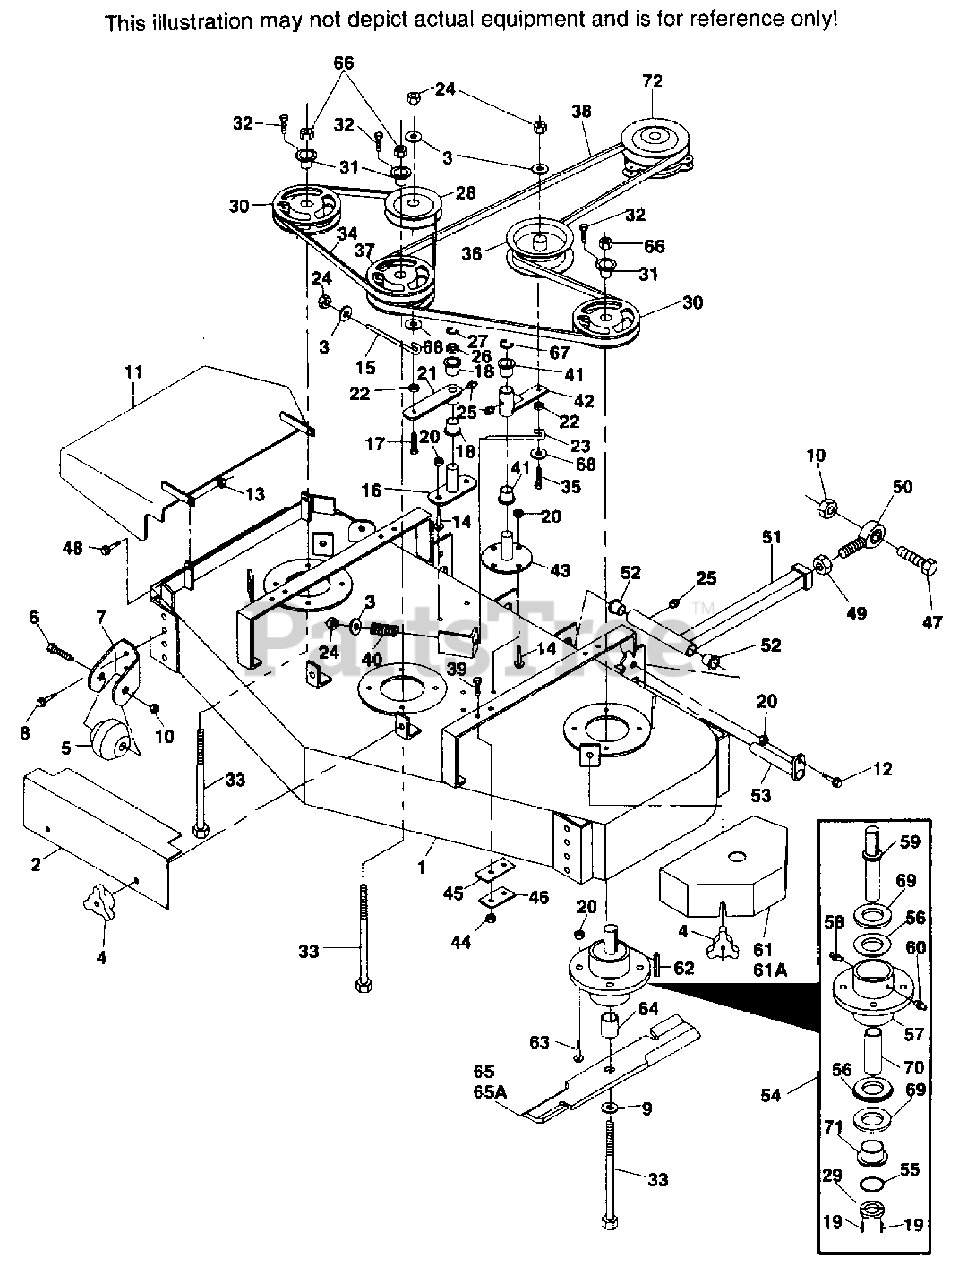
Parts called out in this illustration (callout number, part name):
1	CUTTER DECK(INCLUDES DECALS)
2	BELT COVER, FRONT
3	FLATWASHER, 3/8" SPECIAL
4	WING NUT, 3/8-16
5	ANTI-SCALP WHEEL
7	ANTI-SCALP WHEEL BRACKET
8	CAP SCREW, 3/8-16 X 1" SERRATED FLANGE HEX
9	FLATWASHER 5/8"(.688 X 1.75 X .134)
10	HEX NUT, 5/8-11 ELASTIC STOP
11	DISCHARGE CHUTE
12	CAP SCREW, 5/16-18 X 1" SERRATED FLANGE HEX
13	HEX NUT, 5/16-18 ELASTIC STOP
14	CAP SCREW, 5/16-18 X 3/4" SERRATED FLANGE HEX
15	"J" ROD
16	IDLER PIVOT BASE
18	BUSHING
20	NUT, 5/16-18 SERRATED FLANGE HEX HEAD
21	IDLER ARM,(INCLUDES BUSHINGS & GREASE
22	SPACER
23	"J" ROD
24	HEX NUT, 3/8-16 ELASTIC STOP
25	GREASE FITTING
26	FLATWASHER 3/4"
27	RETAINING RING, 3/4" EXTERNAL "E"
28	PULLEY, IDLER
29	1/4" BLADE SPACER
30	PULLEY
31	TAPERED HUB
33	HEX HEAD BOLT, 5/8-11 X 9-1/2"
34	BELT, RH BLADE DRIVE
36	PULLEY, IDLER - CUTTER ENGAGEMENT
37	PULLEY, DOUBLE
38	BELT, BLADE DRIVE
40	SPRING, IDLER TENSION
41	BUSHING
42	IDLER ARM(INCLUDES BUSHINGS & GREASE
43	IDLER PIVOT BASE
45	RUBBER PAD
46	BACK-UP PLATE
49	HEX NUT, 5/8-18 UNF
50	ROD END
51	PUSH ARM(INCLUDES 25,49,50 & 52)
52	BUSHING
53	PUSH ARM SHAFT
54	CUTTER SPINDLE ASSEMBLY(COMPLETE,
55	RETAINING RING, 1" EXTERNAL, INVERTED
56	BEARING & CUP, TAPERED SPINDLE
57	SPINDLE HOUSING, TAPERED SPINDLE
58	GREASE FITTING
59	SPINDLE SHAFT, TAPERED SPINDLE
60	RELIEF FITTING, TAPERED SPINDLE
61	BELT COVER - RH
61A	BELT COVER - LH
62	KEY, 1/4 X 1/4 X 2"
63	CAP SCREW, 5/16-18 X 1-1/4" SERRATED FLANGE
64	SPACER-TAPERED SPINDLE
65	CUTTER BLADE, 16-1/2" STANDARD
65A	CUTTER BLADE, 16-1/2" HIGH LIFT
67	RETAINING RING 1-1/8" EXTERNAL "E"
68	FLATWASHER, 3/8"(3/8 X 1.5 X .06)
69	SEAL, TAPERED CUTTER SPINDLE
70	SPACER, TAPERED SPINDLE
71	BUSHING, TAPERED SPINDLE
72	ELECTRIC CLUTCH
